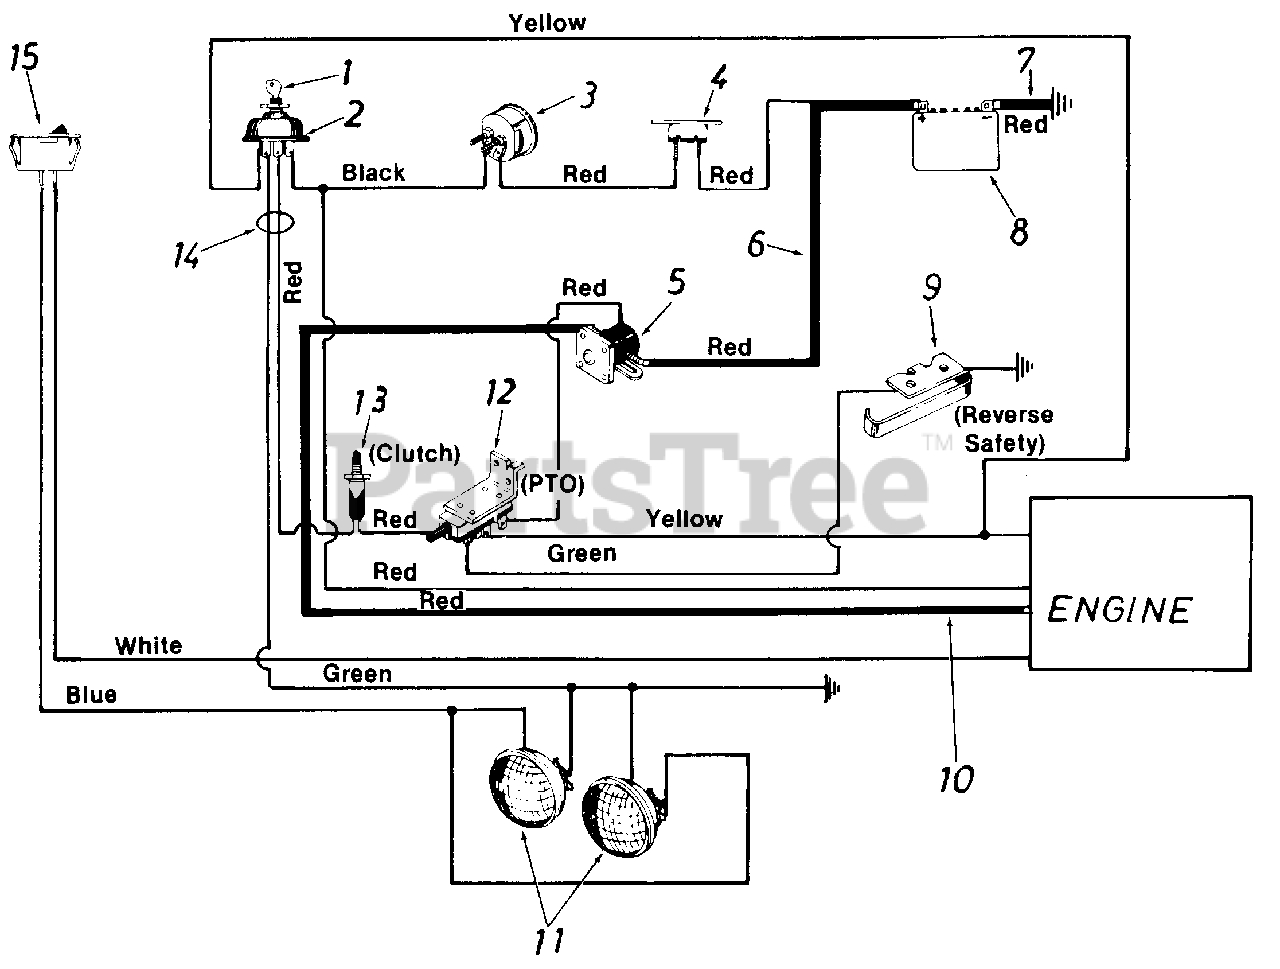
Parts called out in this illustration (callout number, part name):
1	Ignition Key
2	Ignition Switch
3	Ammeter
4	Circuit Breaker
5	Solenoid
6	Electric Wire
7	Electric Wire
8	Battery
9	Spring Switch
10	Electric Wire
11	Headlights
12	Safety Switch
13	Safety Switch
14	Wire Harness
15	Light Switch
